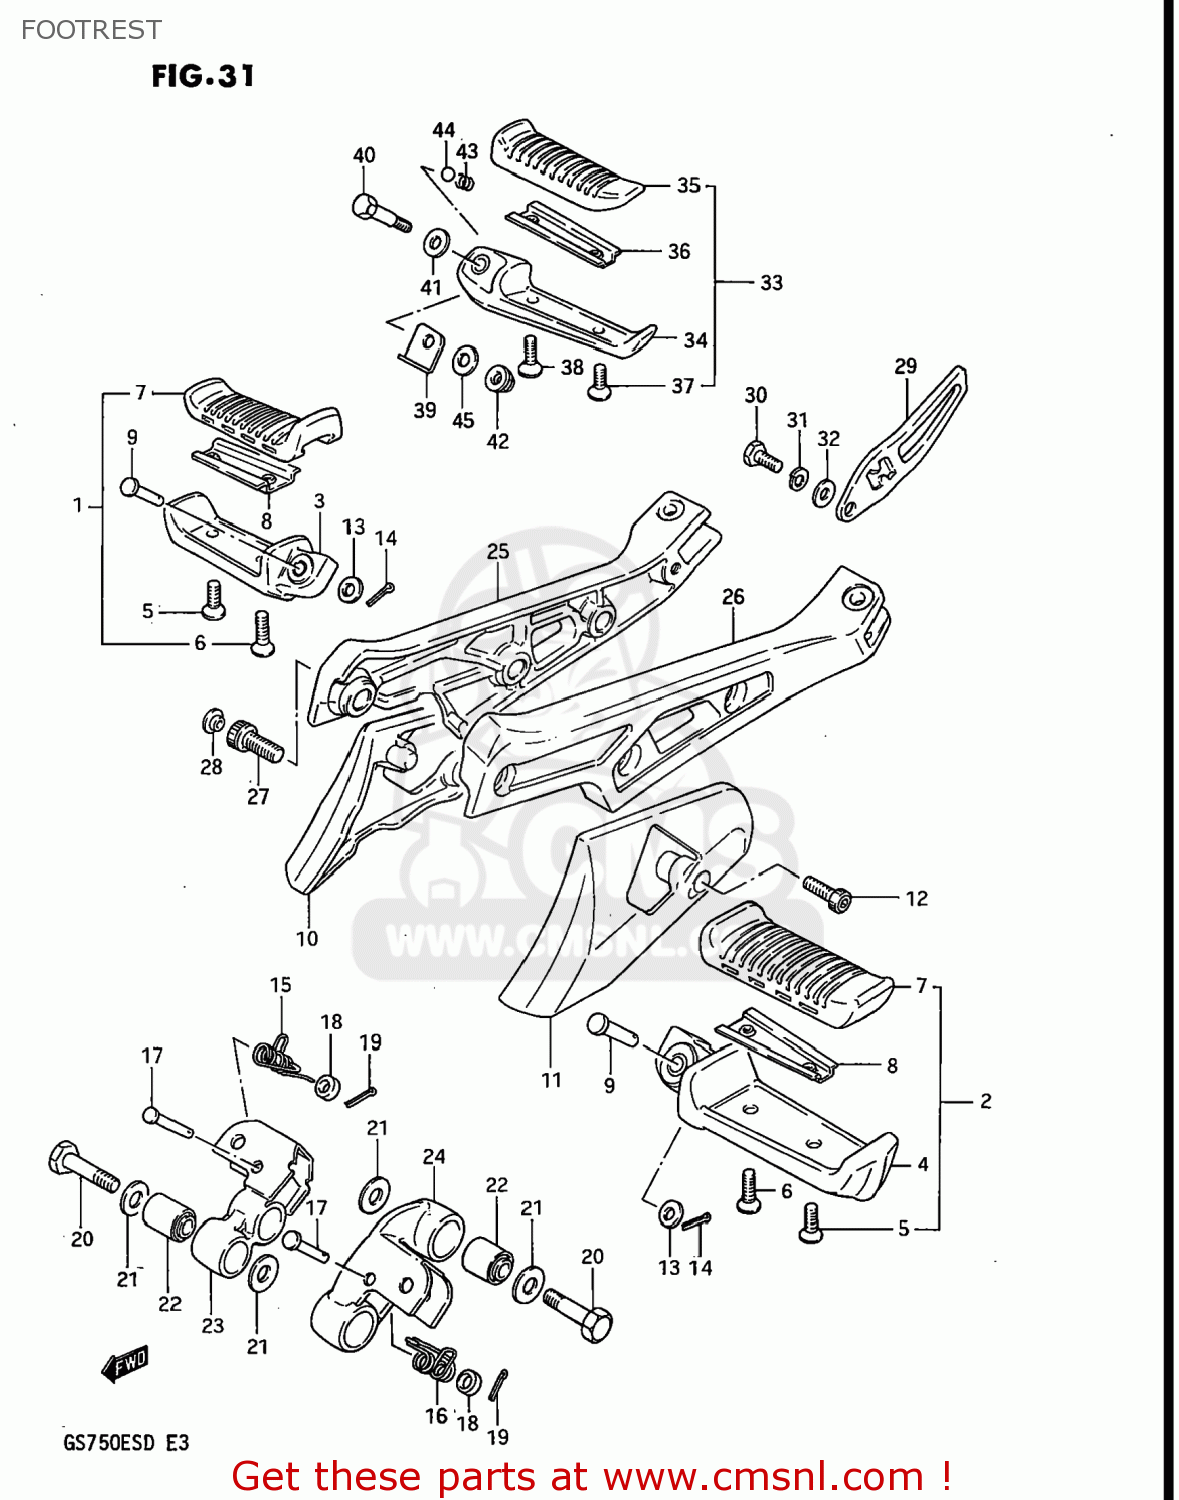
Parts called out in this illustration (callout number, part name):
1	FOOTREST ASSEMBLY,FRONT,RIGHT
2	FOOTREST ASSEMBLY,FRONT,LEFT
3	BAR,FRONT FOOTREST,RIGHT
4	BAR,FR FOOTREST,L
5	SCREW
6	SCREW
7	RUBBER,FOOTREST
8	PLATE,FR FOOTREST RUBBER
9	PIN
10	COVER,FRONT FOOTREST,RIGHT
11	COVER,FRONT FOOTREST,LEFT
12	BOLT
13	WASHER,8.5X16X
14	PIN 20X20
15	SPRING
16	SPRING
17	PIN
18	SPACER (6.5X12X5.5)
19	PIN 20X20
20	BOLT 10X40
21	WASHER(10.5X20X3.2)
22	BUSH
23	HOLDER,FRONT FOOTREST,RIGHT
24	HOLDER,FRONT FOOTREST,LEFT
25	BRACKET,MUFFLER,RIGHT
26	BRACKET,MUFFLER,LEFT
27	BOLT
28	CAP
29	GUARD,REAR FOOT
30	BOLT
31	LOCK WASHER
32	WASHER
33	FOOTREST ASSY,PILLION,R
34	BAR,PILLION FOOTREST,LEFT
35	RUBBER,RR FOOTREST
36	PLATE,RUBBER STOPPER
37	SCREW 5X12
38	SCREW
39	PLATE,SPRING STOP
40	BOLT
41	WASHER
42	NUT
43	SPRING
44	BALL
45	SHIM(8.2X22X0.2)
